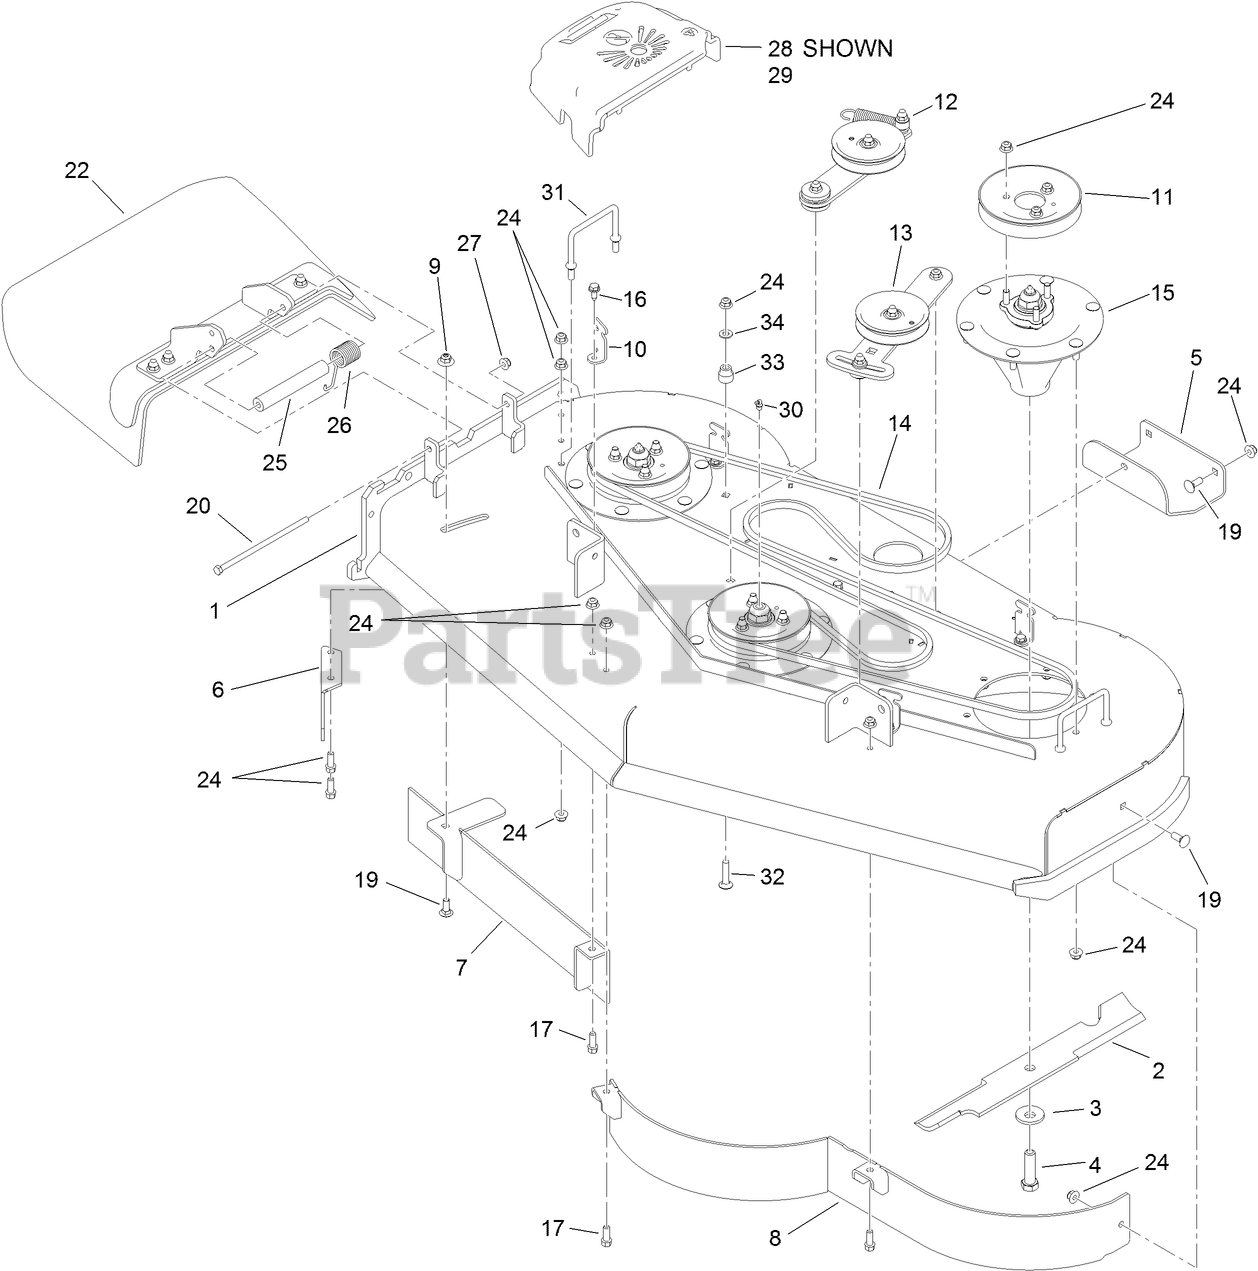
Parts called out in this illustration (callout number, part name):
1	DECK ASM
2	BLADE-18IN, HI FLOW
3	Washer-Blade Bolt, Heavy
4	SCREW-BLADE
6	BAFFLE-DISCHARGE
8	BAFFLE-52 INCH
9	NUT-FLANGE, NI
10	BRACKET-COVER
11	PULLEY
12	IDLER ARM ASM
13	IDLER ADJUST ASM
14	BELT-V
15	SPINDLE ASM
16	SCREW-HWHTF
17	SCREW-HWH
19	BOLT-CARR
20	SCREW-HH
22	DEFLECTOR ASM
24	NUT-HF, NI
25	SPACER
26	SPRING-TORSION
27	NUT-HF, NI
28	COVER-BELT, RH
29	COVER-BELT
30	FITTING-GREASE
31	WIREFORM-COVER
32	SCREW-CARR
33	BUSHING-IDLER
34	WASHER-FLAT
